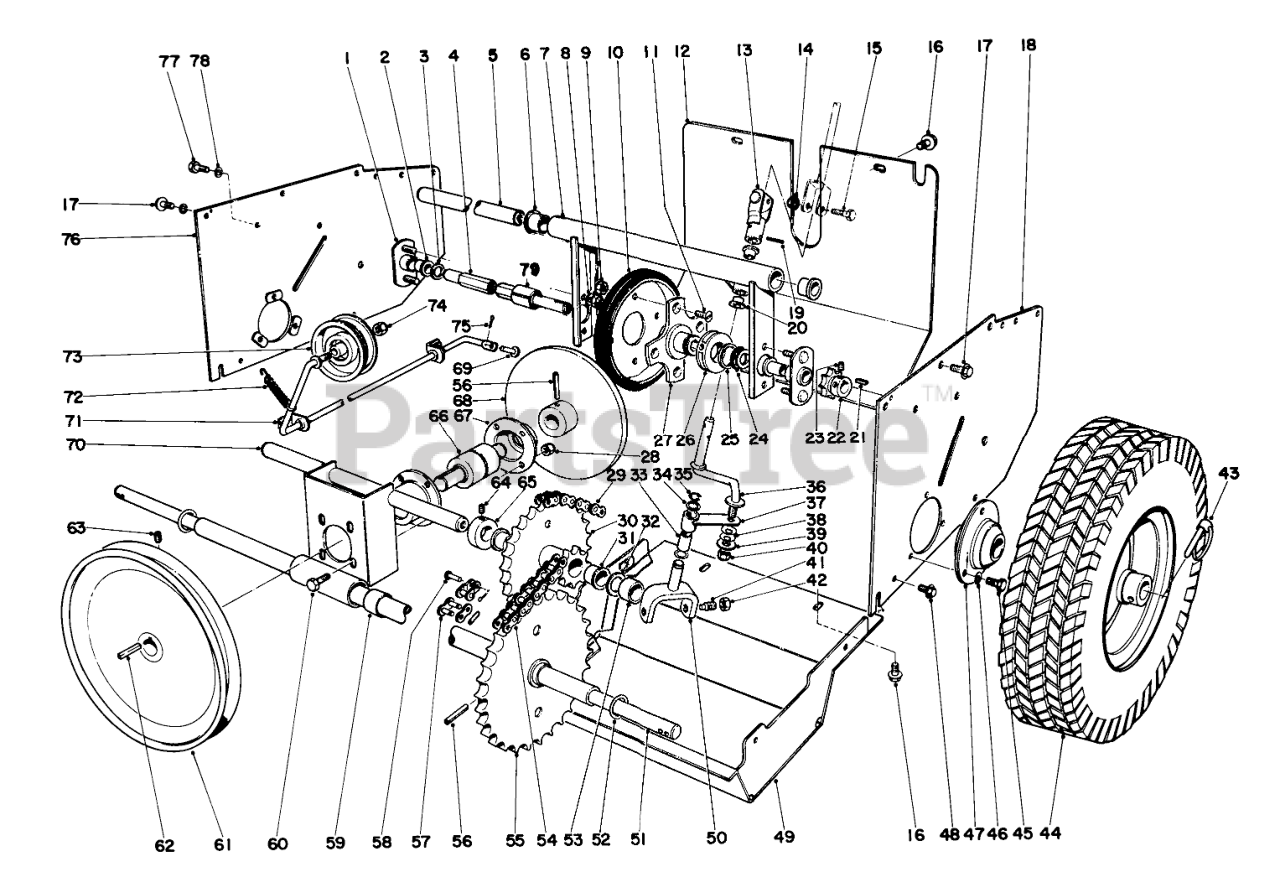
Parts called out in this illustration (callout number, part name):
1	Adjusting Plate (Incl. Ref. No. 2)
2	Bushing
3	WASHER-FLAT
4	Shaft, Friction Wheel
5	Dead Shaft
6	BUSHING-FLANGE
7	Pivot Tube (Incl. Ref. Nos. 6 & 20)
8	WASHER-PLAIN
9	Nut
10	Disc
12	Rear Shield
13	U Joint
14	NUT-LOCK
15	SCREW-HH
16	Machine Screw
17	SCREW-HHF
18	Side Plate, Drive
19	PIN-SPRING
20	3/4IDX1LG FLANGE BSHG
22	SPROCKET
23	Set Screw
24	RING-RETAINING
25	WASHER-THRUST
26	Ring Slider
27	Hub Traction
28	Nut
29	1/4 X 42 CHAIN W/LINK
30	Sprocket & Hub (Incl. Ref. No.31)
31	3/4ID X 3/4LG BSHG
32	WASHER-THRUST
33	Bushing
34	Thrust Washer
35	E-RING
36	Connecting Rod
37	Shift Rod (Incl. Ref. No.33)
38	WASHER-SPRING
39	WASHER-LOCK / EXT
40	NUT-LOCK
41	Set Screw
42	NUT-JAM
43	PIN-LYNCH
44	Wheel
45	SCREW-HH
46	WASHER-LOCK
47	Bearing Flange
48	SCREW-HHF
49	Lower Shield
51	Axle Shaft
52	WASHER
53	Spacer Idler
54	Chain Lower
55	Sprocket
56	PIN-SPIRAL
57	LINK-CONNECTING
58	1/4 OFFSET LINK
59	Bushing
60	SCREW-HH
61	Pulley
62	KEY-SQUARE
63	SCREW-SET, SQH
64	SCREW-HSH
65	Collar
66	Friction Plate Shaft
67	HOUSING BEARING
68	Friction Plate
69	PIN-CLEVIS
70	Bulkhead (Incl. Ref. No. 59)
71	Auger Clutch Rod
72	EXTENSION SPRING
73	PULLEY-IDLER
75	PIN-COTTER
76	Side Plate Drive
77	SCREW-HH
78	WASHER-LOCK
79	SPLIT SPACER
